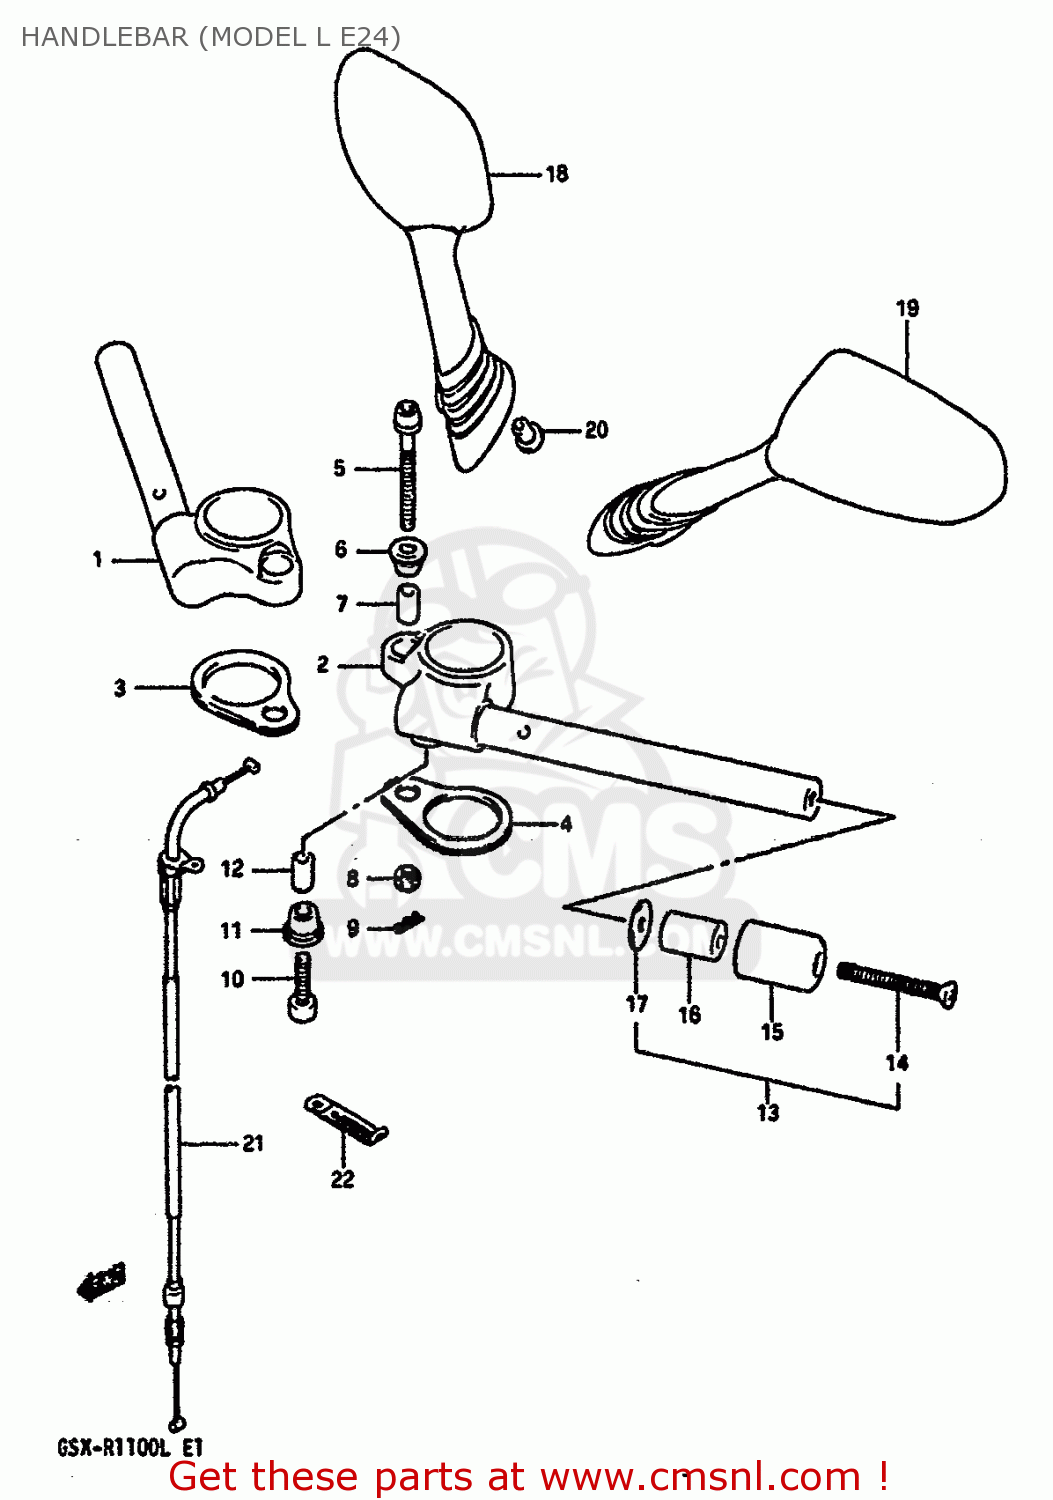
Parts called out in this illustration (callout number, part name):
1	HANDLEBAR,RIGHT
2	HANDLEBAR,LEFT
3	CUSHION,HANDLEBAR,R
4	CUSHION,HANDLEBAR,L
5	BOLT,HANDLEBAR
6	CUSHION,HANDLEBAR UPR
7	SPACER,HANDLEBAR
8	NUT 8MM
9	SNAP
10	BOLT, LH
11	CUSHION,HANDLEBAR UPR
12	SPACER,HANDLEBAR
13	BALANCER SET,HANDLEBAR
14	SCREW (L:65)(SUS)
15	CAP,BALANCER
16	BALANCER,HANDLEBAR
17	SPACER,BALANCER
18	MIRROR ASSY,RR VIEW,R
19	MIRROR ASSY,RR VIEW,L
20	NUT,RR VIEW MIRROR
21	CABLE ASSY,THROTTLE
22	CLAMP
